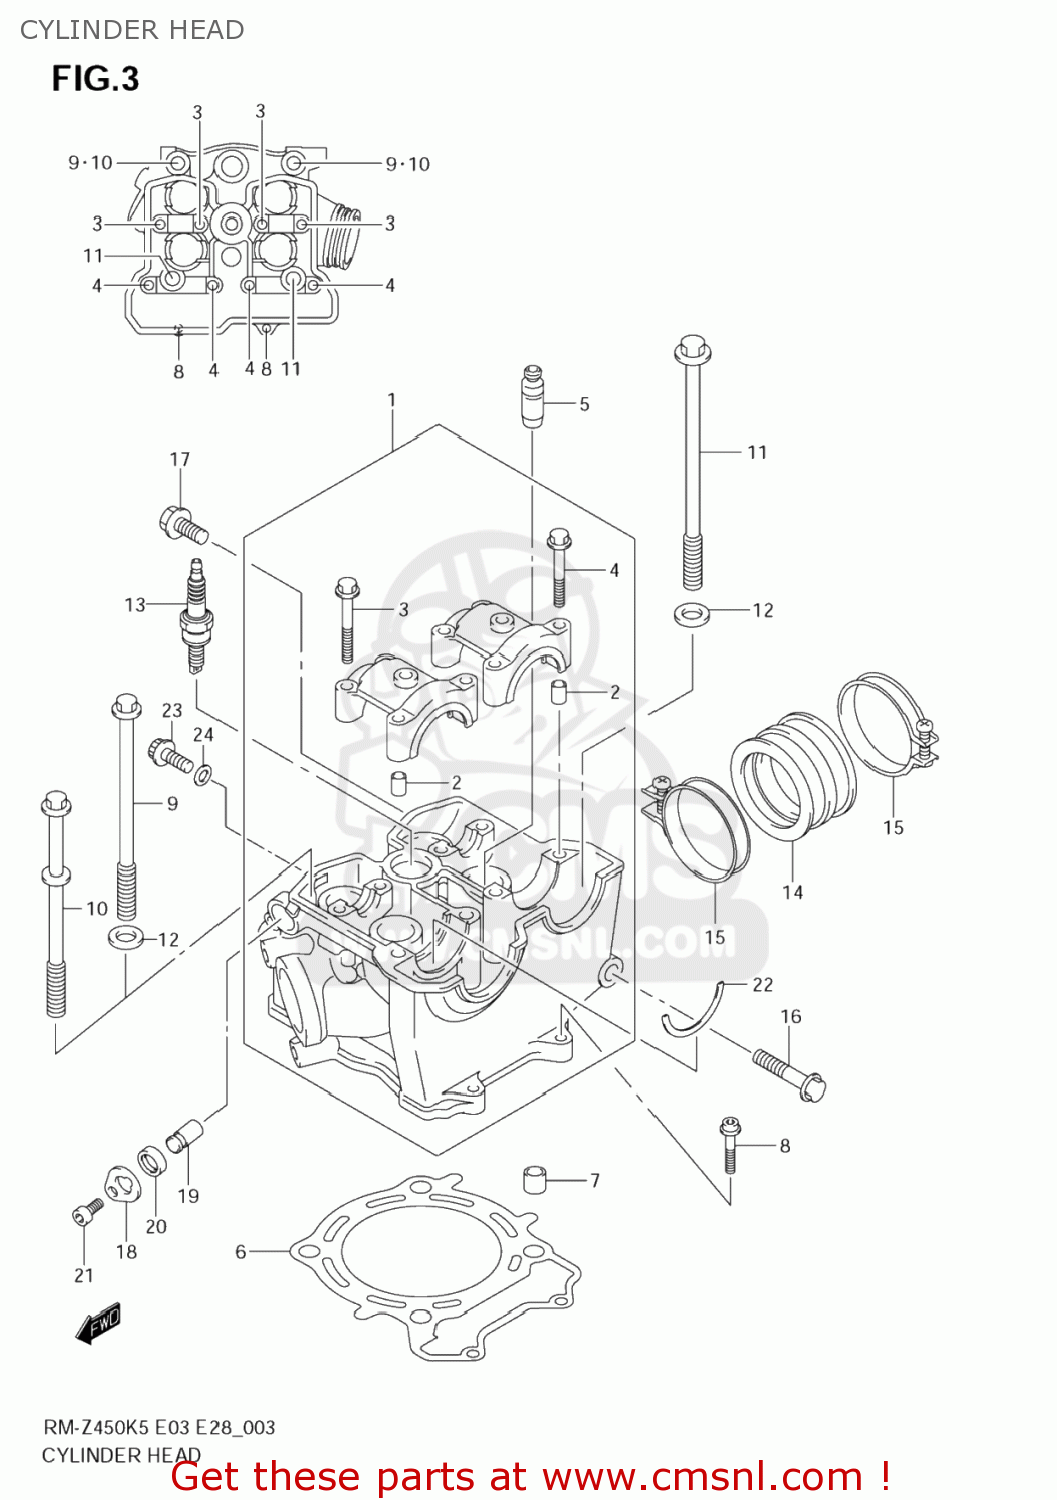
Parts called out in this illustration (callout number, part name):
1	HEAD ASSY,CYLI
2	PIN(6.2X8X11)
3	BOLT(6X39)
4	BOLT(6X45)
5	GUIDE,VALVE
6	GASKET,CYLINDER HEAD (NAS)
7	PIN(10.4X13X18)
8	BOLT,OIL PAN
9	BOLT(10X115)
10	BOLT,CYLINDER HEAD
11	BOLT(10X145)
12	GASKET(10.2X20X2).3 (NAS)
13	PLUG,SPARK(DIMR8A10)
14	PIPE,INTAKE
15	CLAMP
16	BOLT(10X43)
17	BOLT(10X28)
18	RETAINER,DECOMP SHAFT SEAL
19	PLUG,DECOMP SHAFT HOLE
20	SEAL,OIL(10X17X6)
21	BOLT,STRANGER
22	C RING,CAMSHAF
23	BOLT
24	GASKET(6.2X11X1).2 (NAS)
